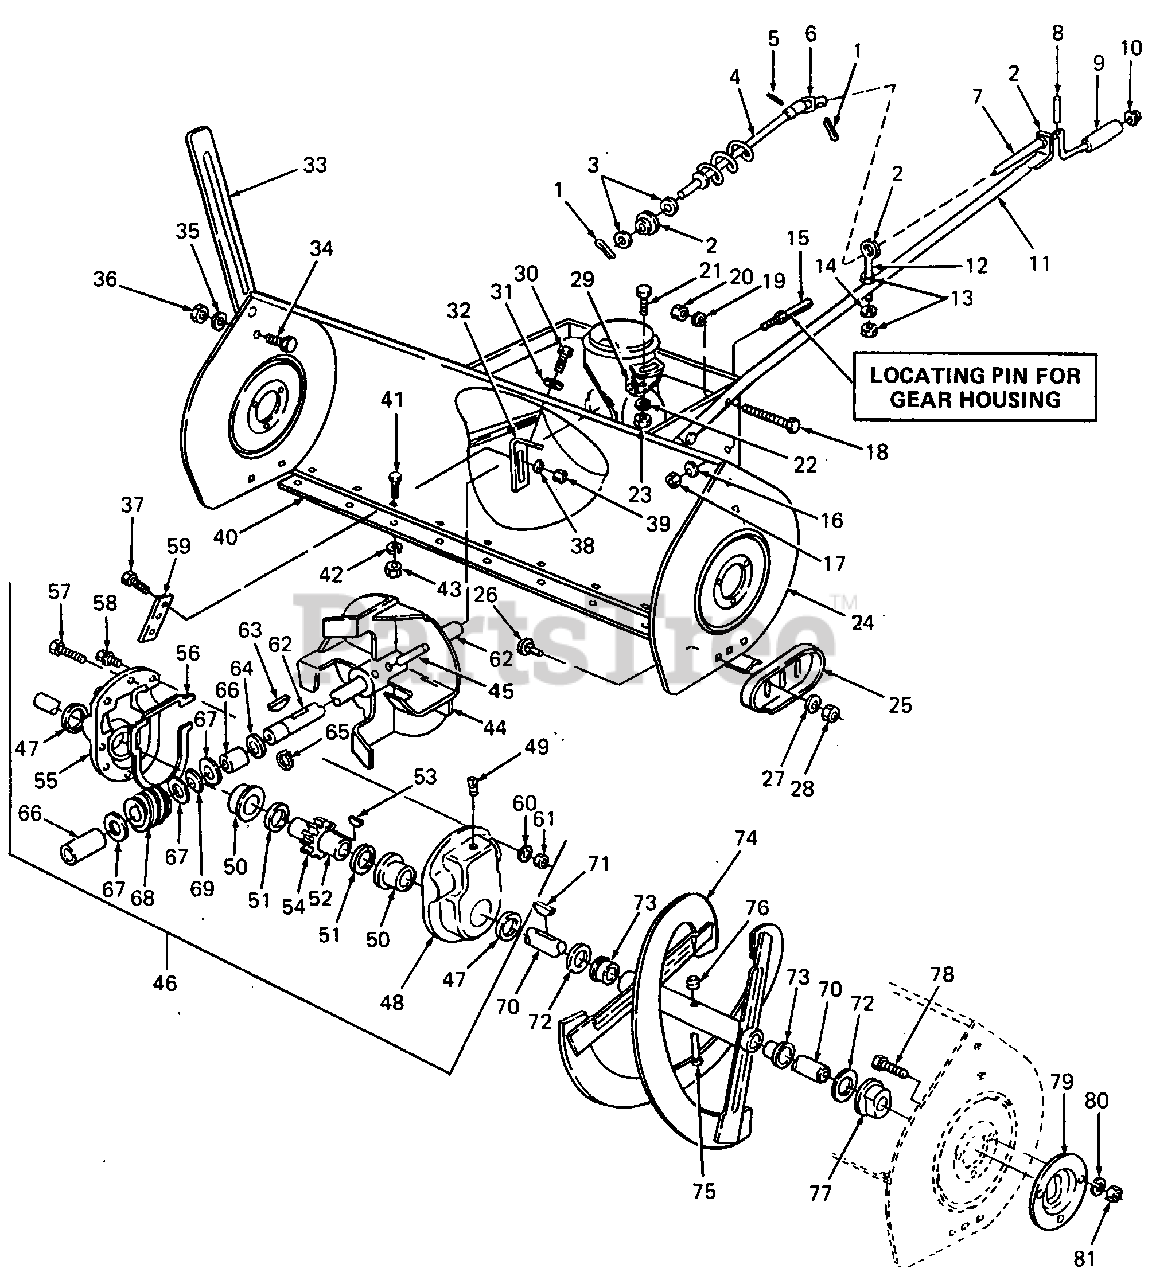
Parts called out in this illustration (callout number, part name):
1	Pin, Cotter, 3/32 Dia X .75 Lg
2	Bushing, Plastic
3	Washer, Flat, .385 X .62 X .063
4	Spiral, Chute Crank
5	Pin, Spiral Spring, 1/8 Dia X .812 Lg
6	Block Assy, Joint
7	Crank, Chute
8	Pin, Roll, 1/8 Dia X .63 Lg
9	Knob, Chute Crank
10	Pushnut, Rod, 3/8
13	Nut, Hex, 5/16-18
14	Washer, Bell, .345 X .88 X .060 Thk
15	Stud, Locating
16	Washer, Flat, .531 X .930 X .050 Thk
17	Nut, Hex Center Lock, 3/8-16
18	Screw, Hex Cap, 3/8-24 X 1.25 Lg GR5
19	Washer, Lock, 3/8
20	Nut, Hex Insert Lock, 3/8-24
21	Bolt, Carriage, 5/16-18 X .75 Lg
22	Washer, Bell, .345 X .88 X .060 Thk
23	Nut, Hex, 5/16-18
24	Housing Assy
25	Shoe, Slide
26	Bolt, Carriage, 3/8-16 X .62 Lg
27	Washer, Flat, .531 X .930 X .050 Thk
28	Nut, Hex, 3/8-16
30	Screw, Hex Wash AB Tapp
31	Washer, Bell, .345 X .88 X .060
34	Bolt, Carriage, 5/16-18 X .75 Lg
35	Washer, Lock, 5/16
36	Nut, Hex, 5/16-18
37	Screw, Hex Cap, 1/4-28 X .75 Lg GR5
38	Washer, Bell, .265 X .75 X .062 Thk
39	Nut, Hex, 1/4-28
41	Bolt, Carriage, 5/16-18 X 1.0 Lg
42	Washer, Lock, 5/16
43	Nut, Hex, 5/16-18
46	Gear Box Assy
47	Seal, Oil
48	Housing, Gear - LH
49	Plug, Vented Plastic
50	Bearing, Flange
51	Washer, Flat, 1.50 X 2.25 X .030 Thk
52	Shaft, Worm Gear
53	Key, Woodruff, 1/4 X 3/4 HDN
54	Gear, Worm
55	Housing, Gear - RH
56	Gasket
57	Screw, Hex Cap, 5/16-18 X 1.25 Lg GR5
58	Screw, Hex Cap, 5/16-18 X 1.0 Lg GR5
59	Plate, Gear Hsg Support
60	Washer, Shake Proof, .32 X .62 X .020 Thk
61	Nut, Hex Insert Lock, 5/16-18
62	Shaft, Blower Axle
63	Key, Hi-Pro, 3/16 X 3/4 HDN
64	Seal, Oil
65	Ring, Snap
66	Sleeve
67	Washer, Flat, .88 X 1.4 X .155 Thk
68	Gear, Worm
69	Bearing, Thrust
70	Shaft, Spiral Axle
71	Key, Woodruff, 1/4 X 3/4 HDN
72	Washer, Flat, 1.0 X 1.75 X .100 Thk
73	Bushing, Plastic
75	Bolt, Shear, 5/16-18 X 1.75 Lg
76	Nut, Hex Insert Lock, 5/16-18
77	Bearing, Flange
78	Bolt, Hex Sems, 5/16-18 X .75 Lg
79	Housing, Bearing
80	Washer, Lock, 5/16
81	Nut, Hex, 5/16-18
